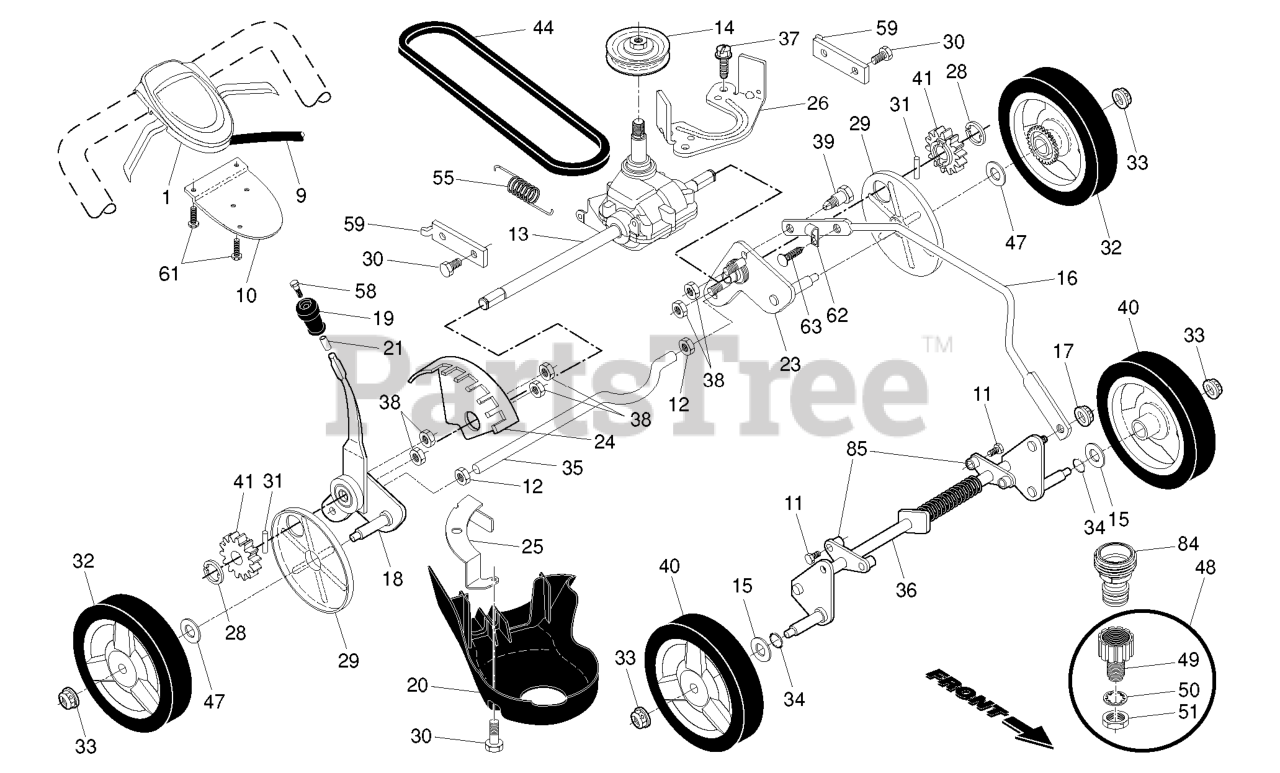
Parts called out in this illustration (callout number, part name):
1	WHEEL ASSY, 16" PWR STR LH
2	PIN KLIK, 1/4
3	COVER
4	SCREW, HEX HEAD, TAPPING
5	NUT.71038.31-18.HEX.NYLOCK
6	WASHER.20X8.5
7	Capscrew, Hex Head, Flanged 3/8-16 x 1
8	BRACKET, STEERING CABLE RH
9	BRACKET, STEERING CABLE LH
11	Screw 5/16-18 x 1/2 Hex, Self Tapping 5/16-18 x 1/2
12	LINK
13	YOKE, STEERING
14	PIN, STEERING LEVER
15	BELLCRANK WELDMENT
16	BRACKET ASS. LH STEERING
17	BRACKET ASSM RH STEERING
18	PIN, STEERING BELLCRANK
19	RETAINER CLIP PM
20	BRACKET.STEER.PNT.BLACK
21	DRIVER, WHEEL
22	RING, WIRE RETAINER
23	LOBE WHEEL
24	SLIDE CLUTCH
25	SPRING, CLUTCH SLIDE
26	LOBE.AXLE.SPLINED
27	KEY
28	WASHER TRUST 1"
29	BEARING, AXLE
30	SPRING
31	WHEEL ASSY, 16" PWR STRG RH
32	RETAINER CLIP
